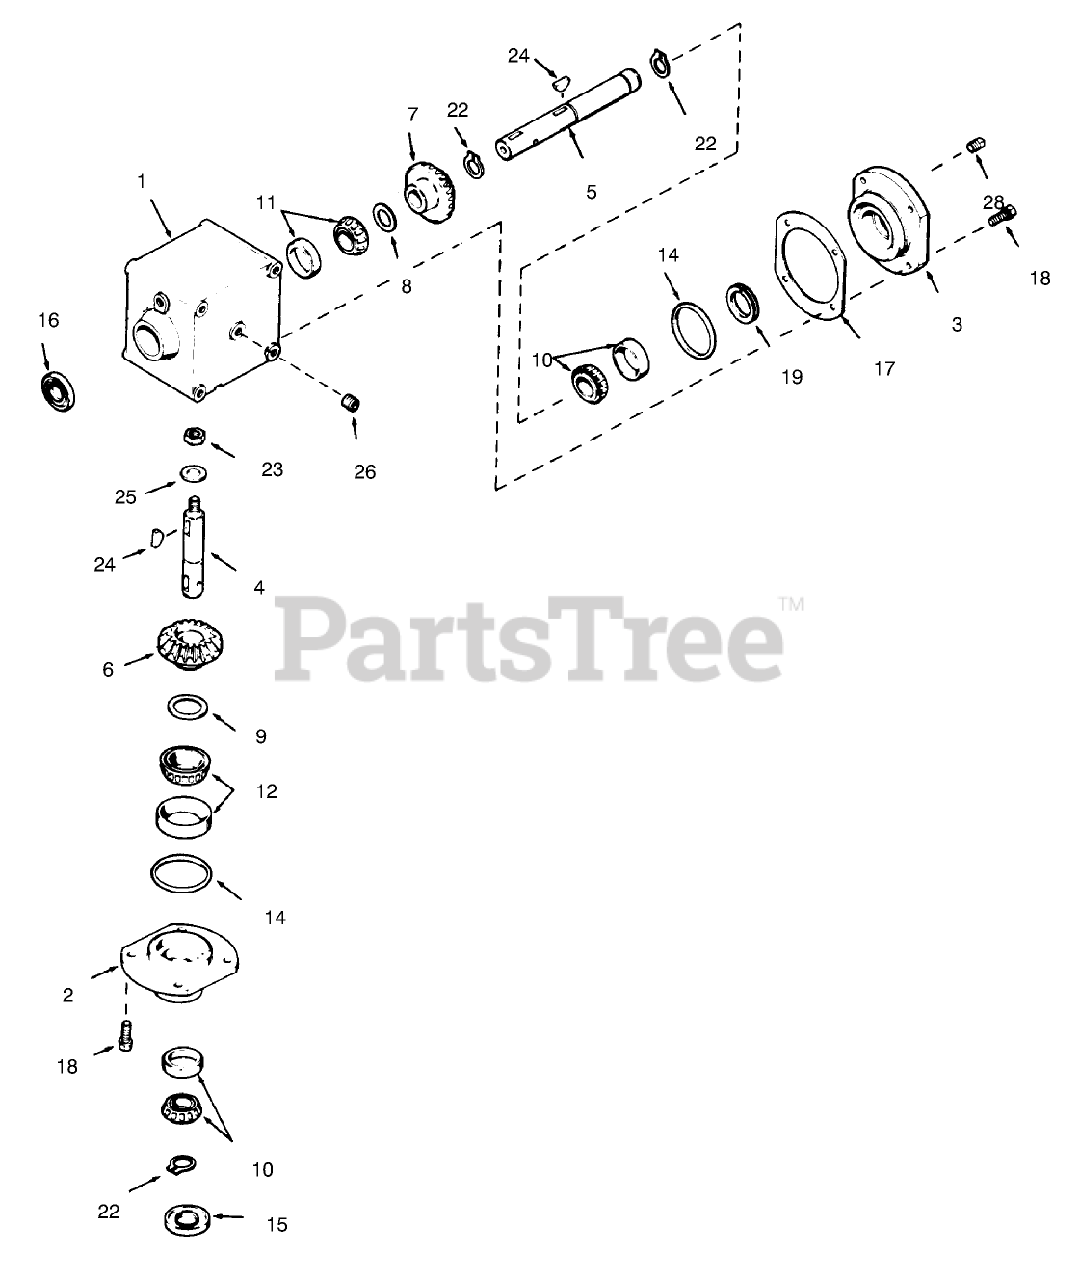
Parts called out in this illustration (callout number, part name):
1	Housing
2	Cap-Retainer
3	Cap-Retainer
4	Shaft-Input
5	Shaft-Output
6	Gear-Bevel 25T
7	Gear-Bevel 26T
8	Shim (1.5" OD x 1.016" ID x .002")
9	Shim (2" OD x 1.531" ID x .002")
10	Bearing & Cup Assembly
11	Bearing & Cup Assembly
12	Bearing & Cup Assembly
14	"O"Ring
15	Seal-Oil
16	Seal-Oil
17	Shim-Oil
18	Screw-Hex Hd.
19	Ring-Load
22	Ring-Retaining
23	Jam Nut
24	Key-Woodruff
25	Washer-Flat
26	Plug-Pipe
28	Plug-Pipe
